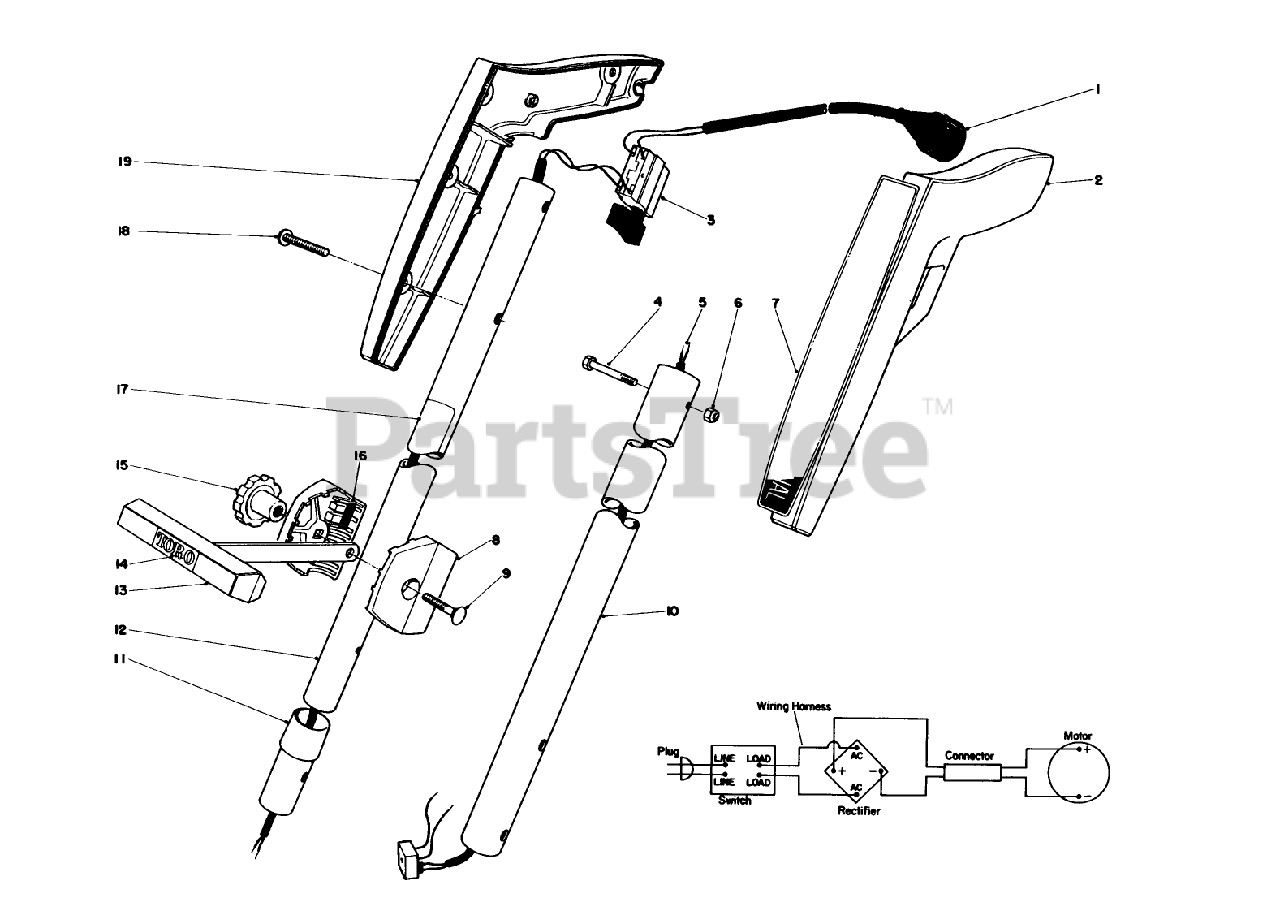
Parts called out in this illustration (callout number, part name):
1	Cord-Power
2	Left Hand Grip
3	Two Speed Switch
4	Screw
5	WIRE HARNESS
6	NUT-LOCK, NI
7	Decal
8	Bracket
9	BOLT-CARR
10	Lower Tube
11	Tubing Sleeve
12	Tube-Upper
13	Tee Handle
14	DECAL - TORO
16	RUBBER INSERT
17	REP. SERIAL PLT
18	Screw
19	Right Hand Grip
